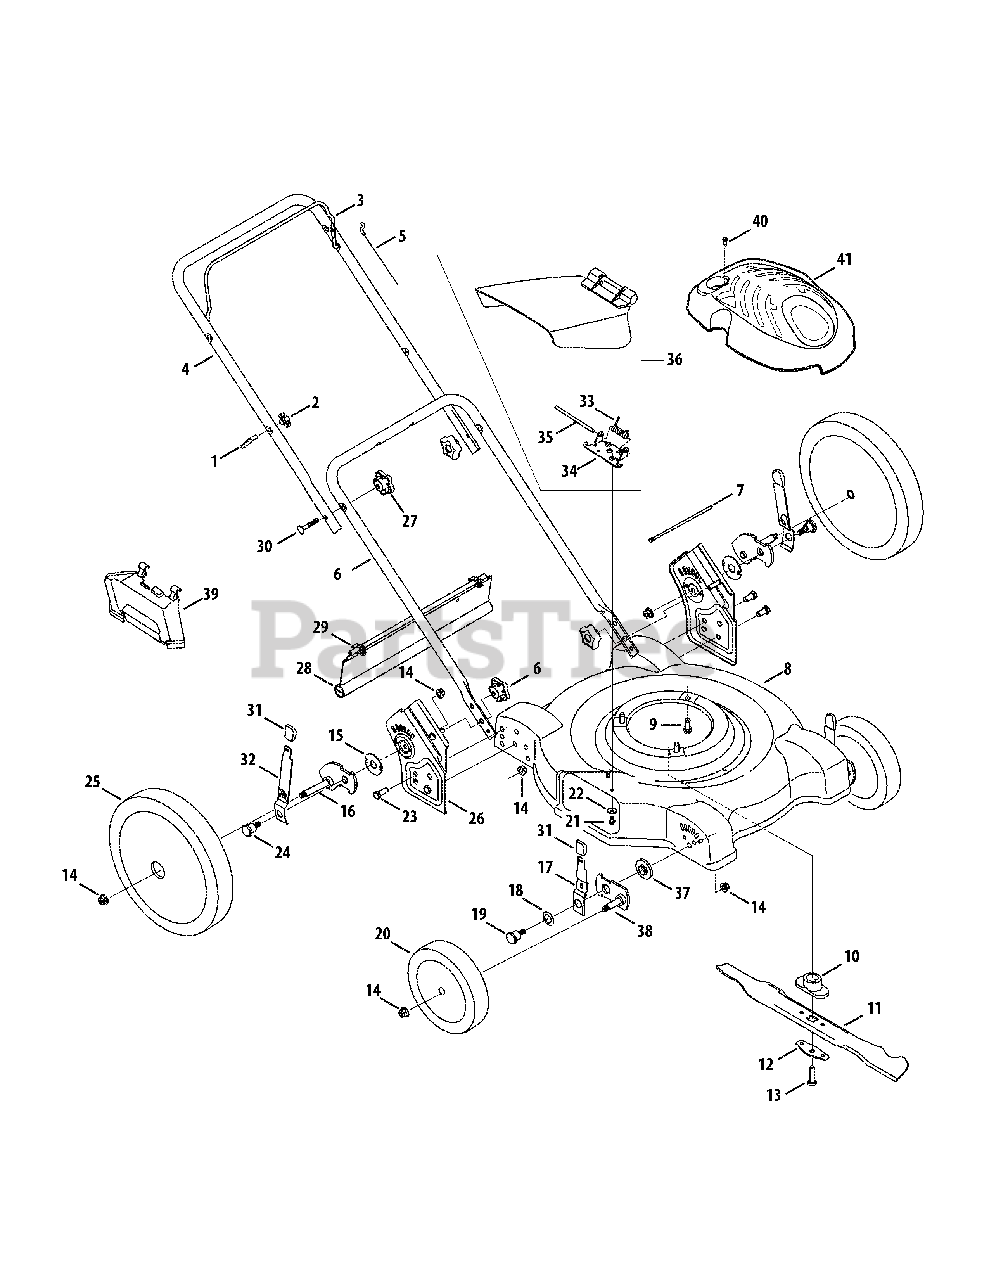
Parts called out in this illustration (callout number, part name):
1	Eye Bolt
2	Wing Nut
5	Control Cable
7	Cable Tie
9	TT Screw, 3/8-16 x 1.0
10	Blade Adapter
11	Mulching Blade, 22"
12	Blade Bell Support
13	Screw, 3/8-24 x 1.5
14	Lock Nut, 3/8-16
15	Thrust Bearing
16	Rear Pivot Arm - RH
17	Front Lever
18	Bell Washer, .760 OD x 1.25 OD
19	Shoulder Screw
20	Front Wheel
21	TT Screw, 1/4-20 x .5
22	Bell Washer, .265 ID x .75 OD
23	Screw, 3/8-16 x .75
24	Shoulder Screw
25	Rear Wheel
28	Trailshield
29	Hinge Clip
30	Carriage Bolt, 5/16-18 x 2
31	Knob
32	Rear Lever
33	Torsion Spring
34	Chute Hinge
35	Hinge Pin
36	Hinged Chute Deflector Assembly
37	Height Adjuster Bearing
38	Front Pivot Arm
39	Mulching Baffle
40	Screw, Machine, M4-.7
41	Engine Shroud
